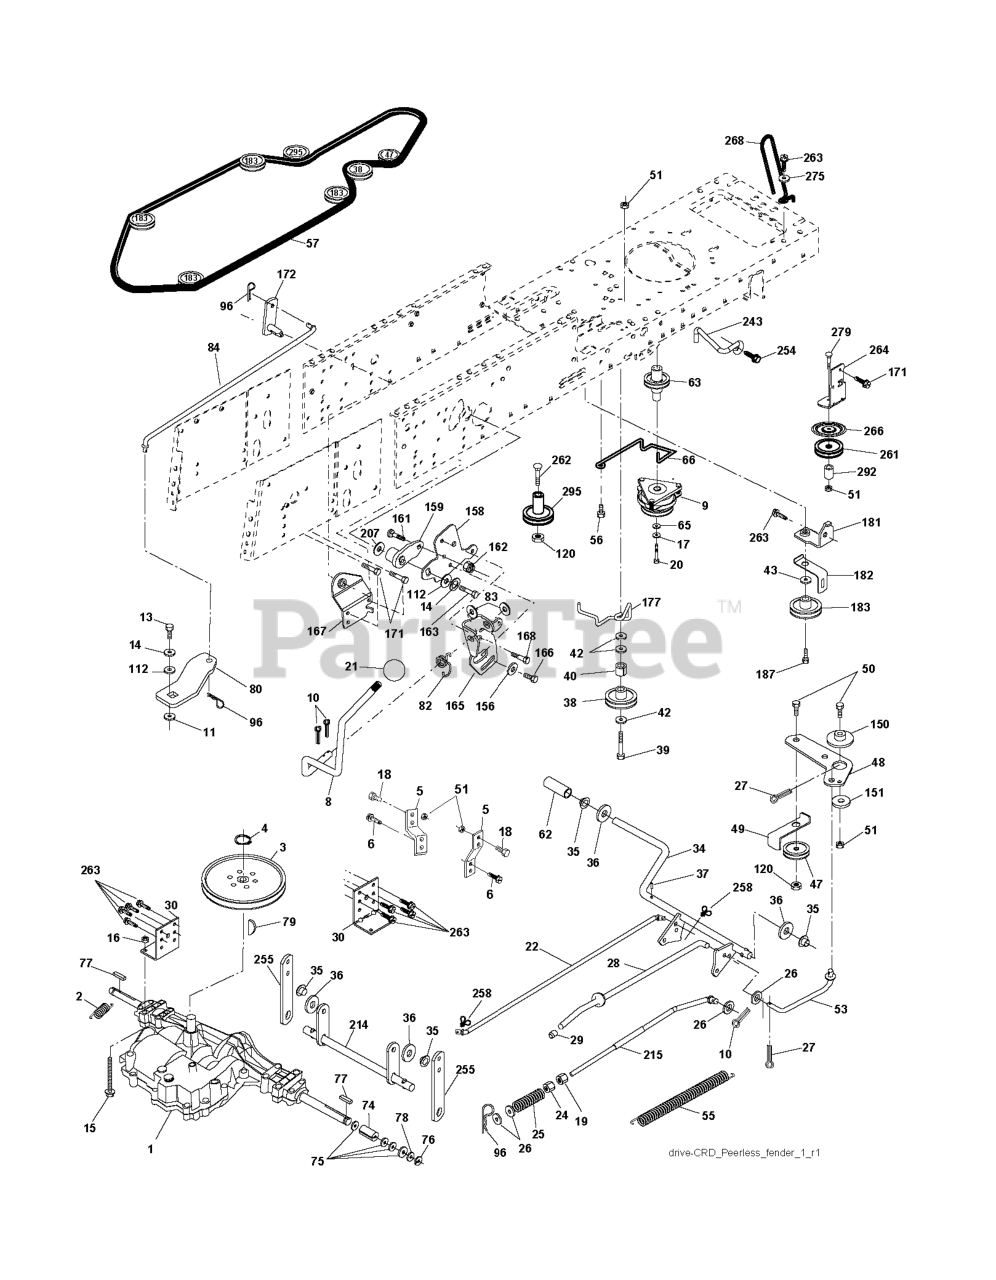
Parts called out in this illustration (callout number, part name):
2	SPRING,BRAKE RETURN
3	PULLEY
4	RETAINING RING LT
5	STRAP TORQUE
6	SCREW 5/16"
8	ROD SHIFT FENDER ADJUST LT
9	CLUTCH.ELECTRIC.OGURA.EURO.
10	PIN COTTER
11	WASH-SHFT PLT LT
13	BOLT 1/4-28X3/4
14	LOCKWASHER
15	BOLT HEX 5/16-18 GR 5
16	NUT.71038.31-18.HEX.NYLOCK
19	NUT
20	BOLT HEX 7/16-20X4-1/4"
21	KNOB.DUCKHEAD.1/2
22	ROD
24	NUT
25	SPRING ROD LT
26	WASHER
27	COTTER PIN
28	ROD, PARKING BRAKE
29	CAP
30	BRKT, MOUNT TRNSAXLE
34	SHAFT, FOOT PEDAL
35	BEARING.NYLON
37	DRIVE PIN
38	PULLEY.FLAT
42	WASHER
47	IDLER PULLEY
48	BELLCRANK, CLUTCH
49	RETAIN BELT
50	BOLT.3/8-16X1.50
53	LINK.CLUTCH.7.66.2005
55	SPRING, RETURN LT
56	SCREW.3/8-16
57	V-BELT.KEV.111"
62	PEDAL COVER T
63	PULLEY.ENGINE.CVX.LT
65	LOCKWASHER
66	KEEPER BELT ENGINE
74	SPACER AXLE
77	SQUARE KEY
79	KEY STD (1373) DANA
82	SHIFT SPRING
83	WASHER
96	RETAINER M
120	NUT LOCK FLG 3/8-16 UNC
150	BUSHING.BELLCRANK.GRD.DR
151	WASHER 12/32X2X10GA
156	WASHER.SRRTD.5/16
158	BRACKET
159	RB HUB.SHIFT
161	BOLT
162	NUT.CROWNLOCK.1/4
165	RP BRACKET
166	CAPSCREW.HXHD.FLG.5/16-18X.625
167	BRACKET.SUPT.SHIFT.CRD
168	BOLT.SHOULDER.5/16-18X
172	SHAFT
181	BRACKET
182	BELT GUIDE
183	PULLEY.V-IDLER.GRND.DR
187	BOLT.5/16-18X1.25
207	WASHER NYL
214	LEVER
243	BRACKET, ANTI-ROTATION
254	SCREW 3/8-16X1
255	SHAFT
258	CLIP RETAINER
261	FLAT IDLER PULLEY
263	SCREW, 3/8-16X3/4
266	PROTECTOR
268	GUARD MUFFLER
275	WASHER
292	SPACER
295	PULLEY IDLER COMPOSITE
